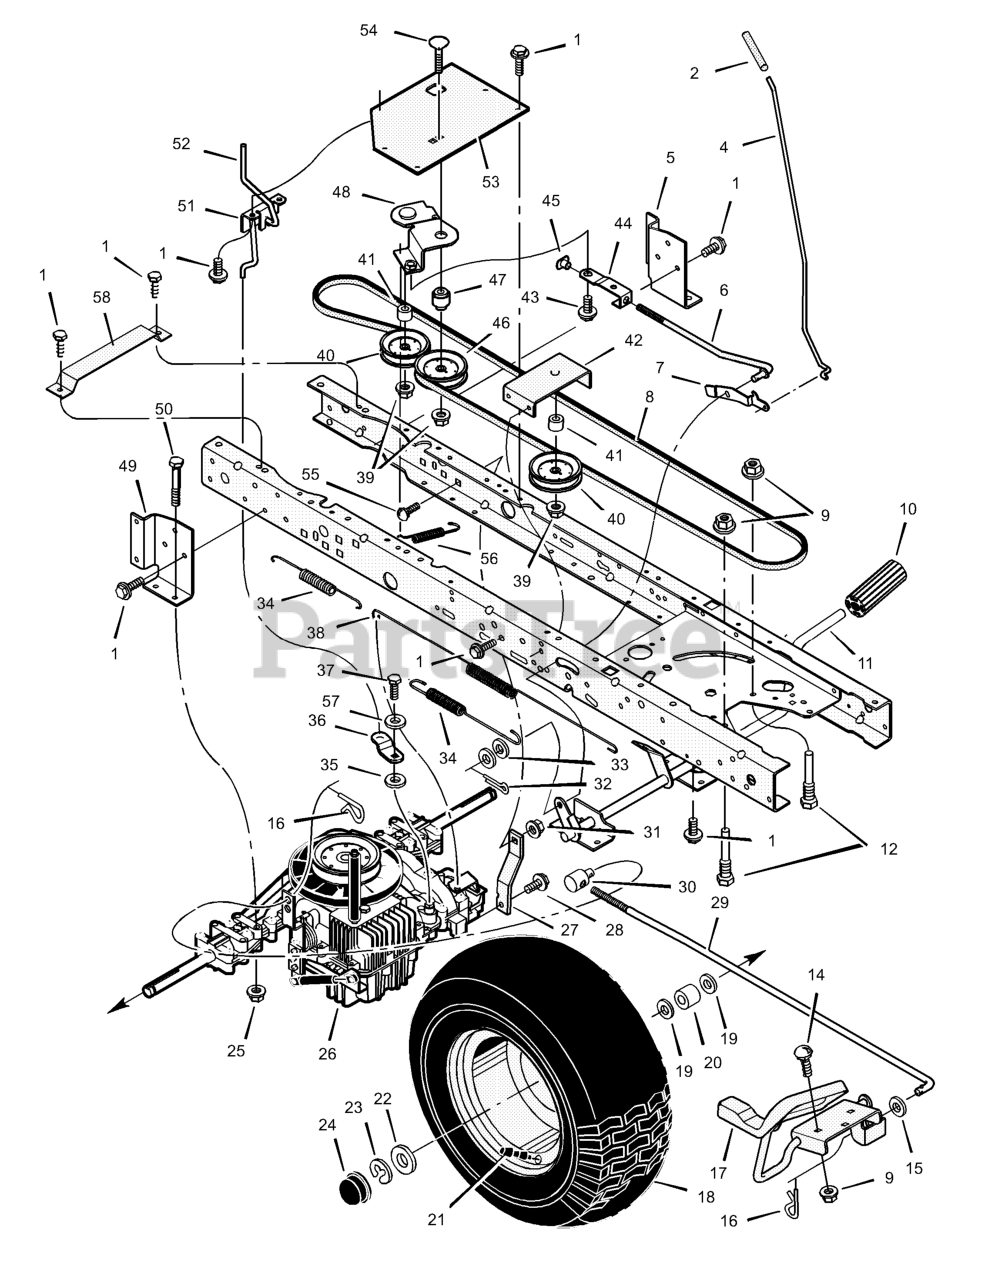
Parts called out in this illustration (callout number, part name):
2	Grip, Parking Brake
4	Rod, Parking Brake
5	Bracket, Left Transaxle
6	Rod, Clutch
7	Latch, Parking Brake
8	V-Belt, Drive
9	Nut, Flange
10	Pedal, Brake/Clutch
11	Assembly, Brake Pedal
12	Screw, Guide
14	Bolt, Carriage
16	Pin, Hair
17	Pedal Assembly, Hydro
18	Wheel & Tire Ass'y - Rear 20"
20	Spacer
21	Stem, Valve
24	Cap, Hub
25	Nut, Centerlock
26	Transaxle **
27	Strap, Torque
29	Rod, Control
30	NUT, Adjusting, 1/2-13
31	Nut, Centerlock
32	Pin, Cotter
34	Spring, Extension
36	ARM, Disconnect
37	Capscrew
38	Spring, Brake
39	Locknut, Flange
40	Pulley, Idler
42	Bracket, Idler Assembly
43	Bolt, Shoulder
44	Link, Clutch
45	Nut, Tee
46	Pulley, Idler
47	Bushing, Pivot
48	Arm Assembly, Idler
49	Bracket, Right Transaxle
50	Bolt, Hex
51	Bracket, Disconnect
52	Rod, Disconnect
53	Bracket, Idler Pivot
54	Bolt, Carriage
55	Bolt, Carriage
56	Spring, Clutch
58	Bracket, Battery Support
